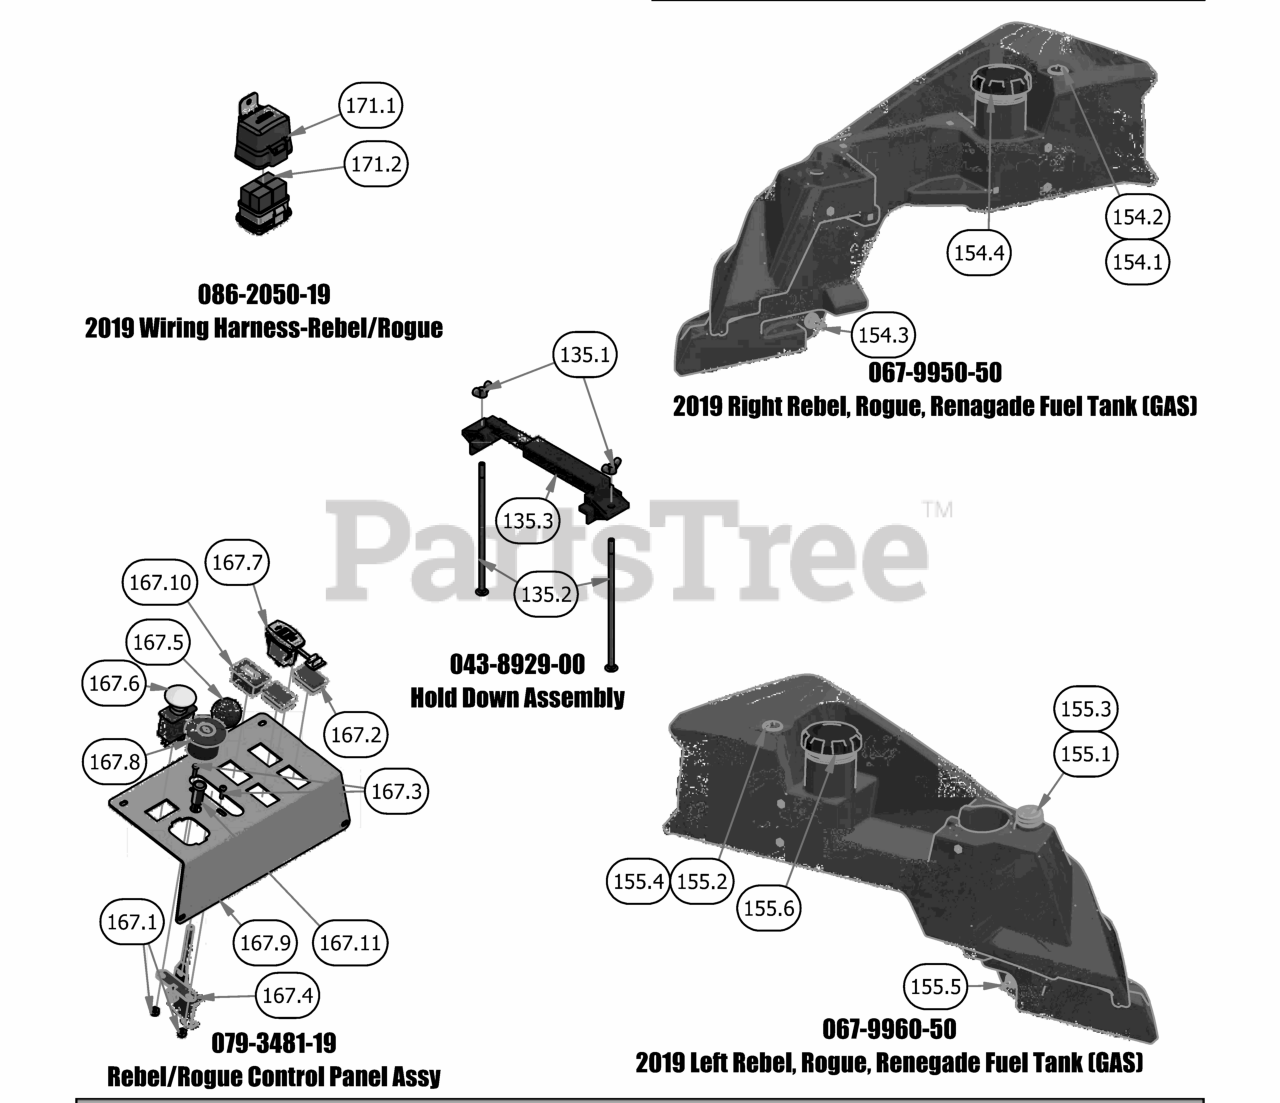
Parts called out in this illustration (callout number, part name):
135.1	1/4" Wing Nut
135.2	1/4-20 X 8 Carriage Bolt
135.3	Battery Hold Down
154.1	Roll Over Valve Grommet
154.2	Rollover Valve
154.3	Fuel Pick-up
155.1	Fuel Gauge with Grommet
155.2	Roll Over Valve Grommet
155.3	Fuel Gauge Grommet
155.4	Rollover Valve
155.5	Fuel Pick-up
167.1	10-24 Nylon Insert Locknut Zinc Orange Nylon
167.2	Light Plug
167.3	10-24 X 5/8 BS Button Head Bolt
167.4	Universal Throttle
167.5	Throttle Knob
167.6	PTO Switch
167.8	Ignition Switch
167.9	2019 Outlaw Control Panel
167.10	Tachometer
171.1	Relay Block Cover Replacement Kit
